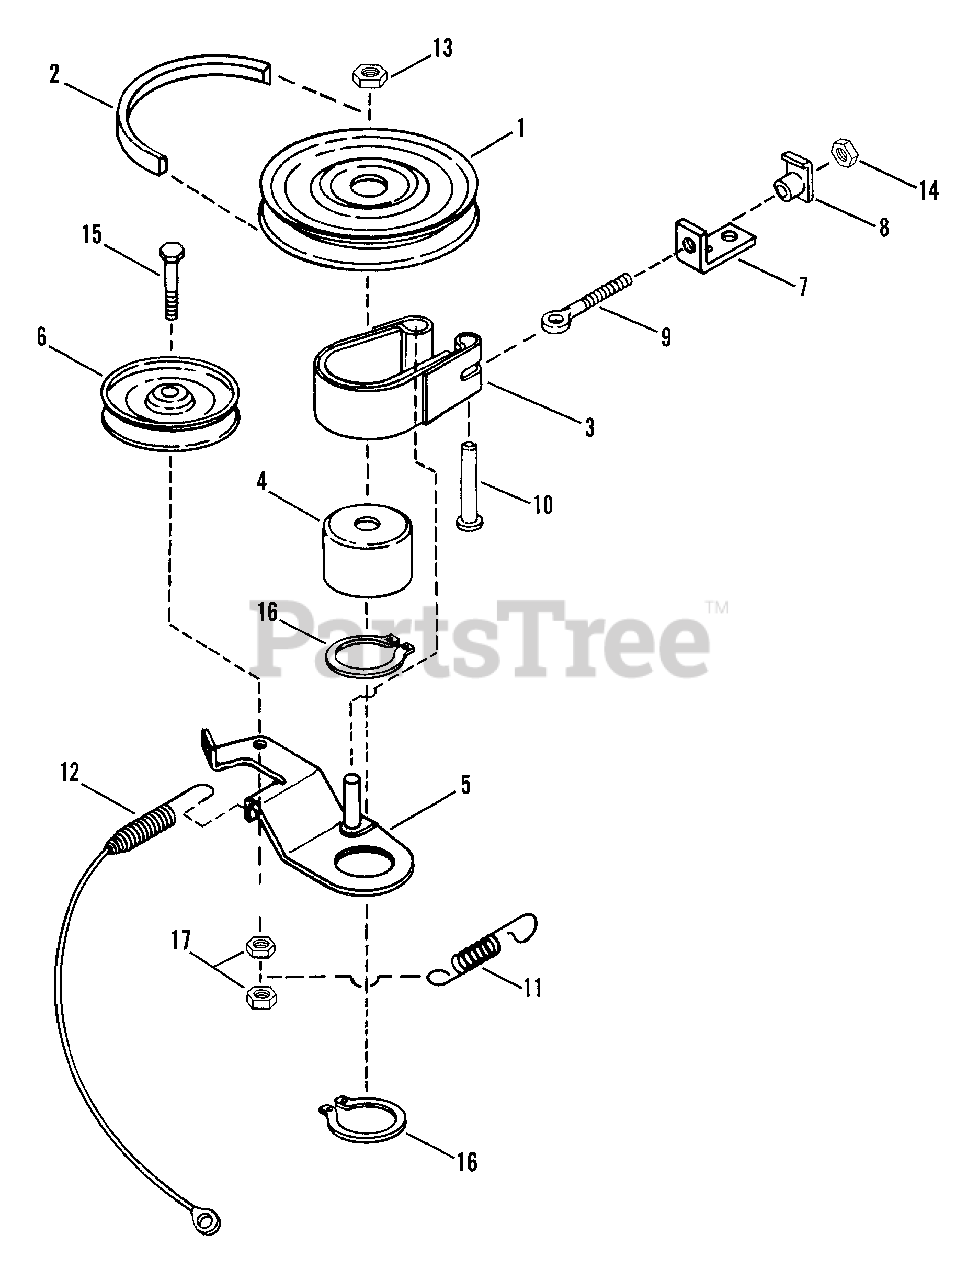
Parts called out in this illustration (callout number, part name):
1	PULLEY, Drive
2	BELT, Drive
3	BAND, Brake Assembly
4	DRUM, Brake
5	ASSEMBLY, Brake Arm
6	PULLEY, Idler
7	ANCHOR, Brake
8	NUT, 1/4-20 Tec.
9	BOLT, 1/4-20 Eye
10	PIN, Clevis, 1/4x1-1/4"
11	SPRING, Blade Brake
12	CABLE, Blade 28.5"
13	NUT, 3/4-16 Hex Jam
14	NUT, 1/4-20 Hex
15	SCREW, 3/8-24x2" Hex Head Cap (Gr. 5)
16	RING, 2" External Retaining
17	NUT, 3/8-24 Hex Lock
